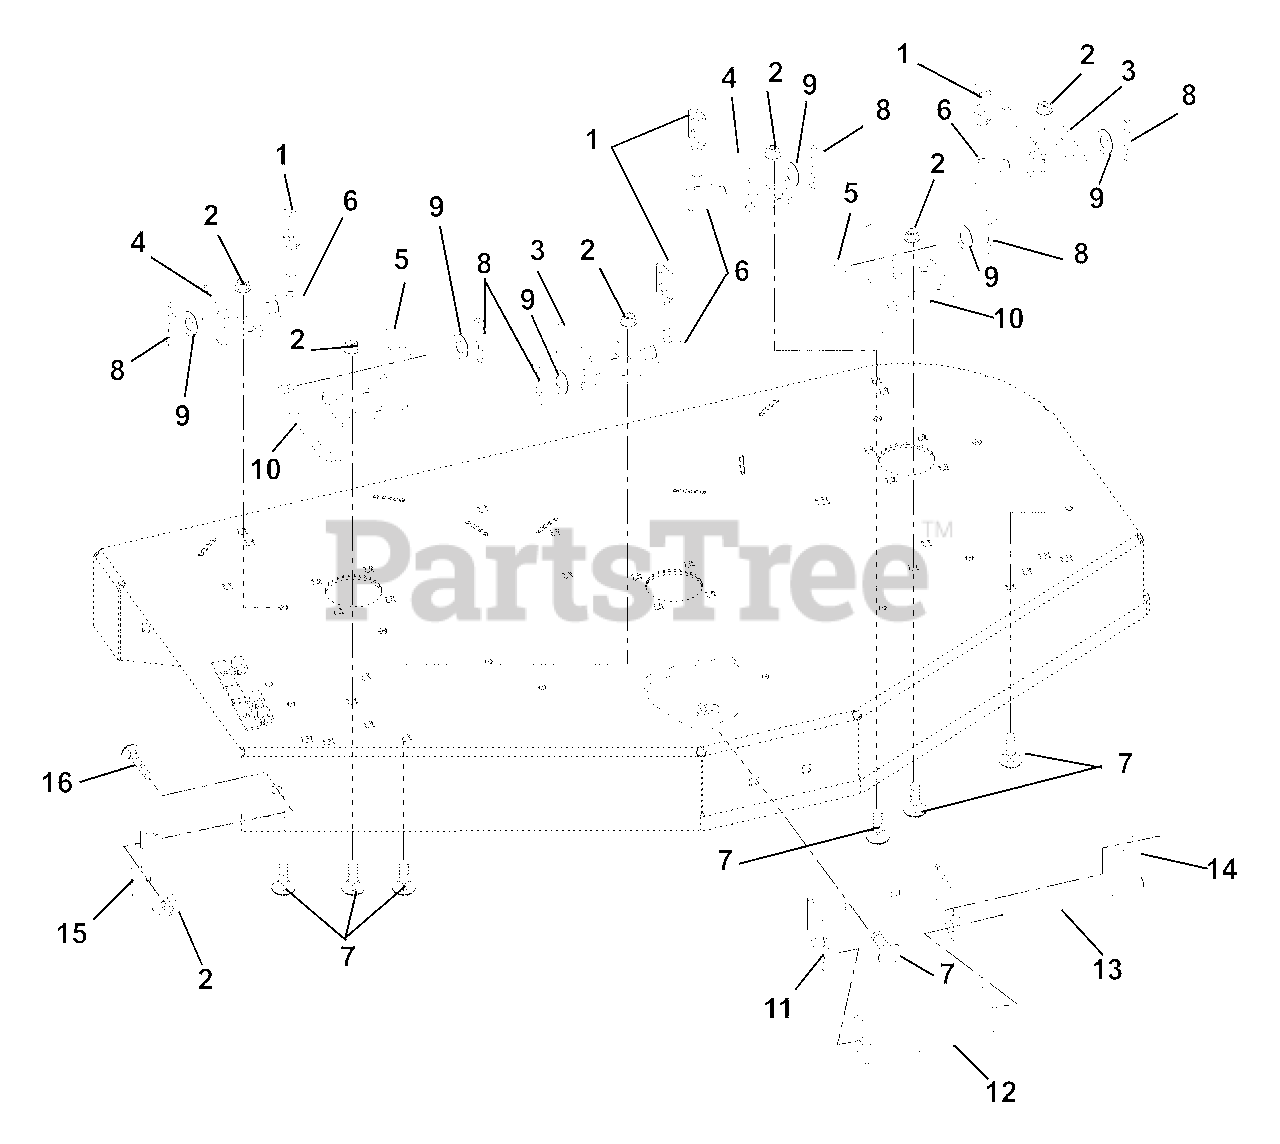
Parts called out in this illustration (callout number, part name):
1	Deck Link
2	Nut .38-16 Flange Nyloc
3	Bracket, Mount, Front
4	Bracket, Rear Mount
5	Bracket, Stabilizer
6	Trunnion
7	Bolt, Round Head Square Neck .38-16 x 1.00 Grade 5
8	Pin, Hair, External
9	Washer-Flat-STL.511 x 1.441 x .125
10	Rod, Drag Link
11	Bracket, Roller Mount
12	Roller
13	Pin, Roller
14	Pin, Spring Clip
15	Bracket, Chute Lock
16	Bolt, Round Head Square Neck .38-16 x 1.25
